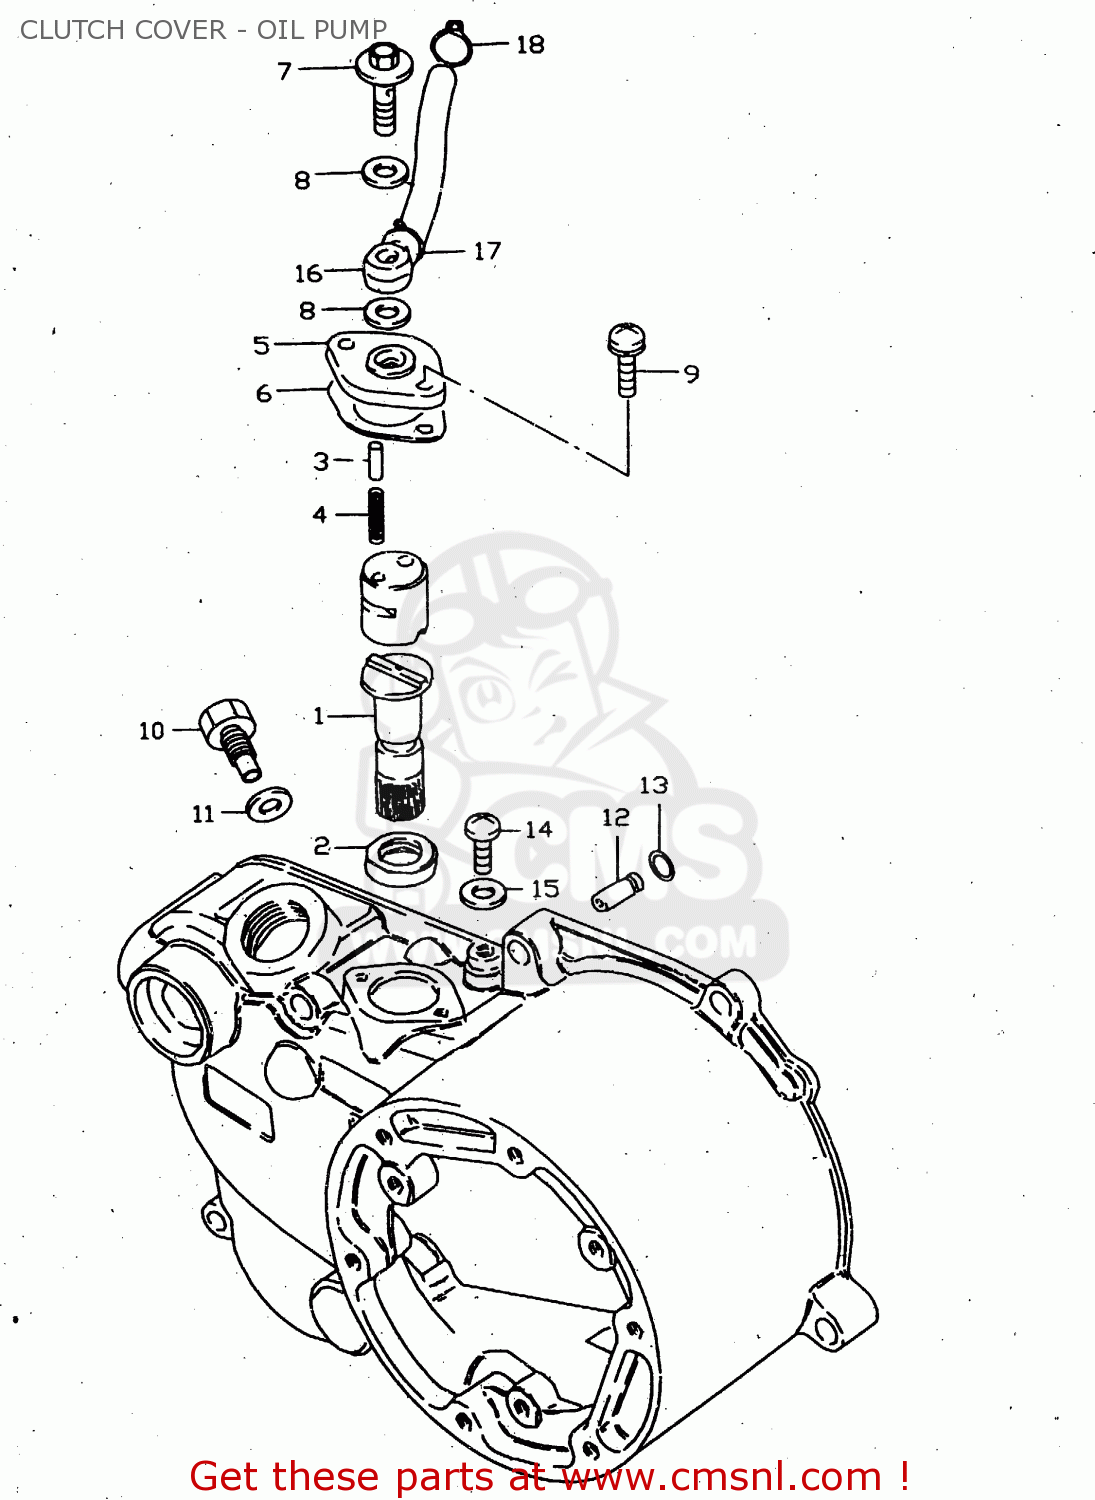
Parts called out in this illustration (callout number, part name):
1	GEAR,OIL PUMP DRIVE
2	SEAL,OIL(12X18.5X3)
3	PIN(2.3X7.5)
4	SPRING
5	CAM,OIL PUMP
6	GASKET,OIL PUMP (NAS)
7	UNION BOLT
8	GASKET (NAS)
9	SCREW
10	BOLT(6X10)
11	WASHER
12	VALVE,CRANK CHECK
13	O RING(D:1.05,ID:3.1)
14	SCREW
15	GASKET(5X9.5X1) (NAS)
16	HOSE,INLET
17	CLIP
18	CLIP
